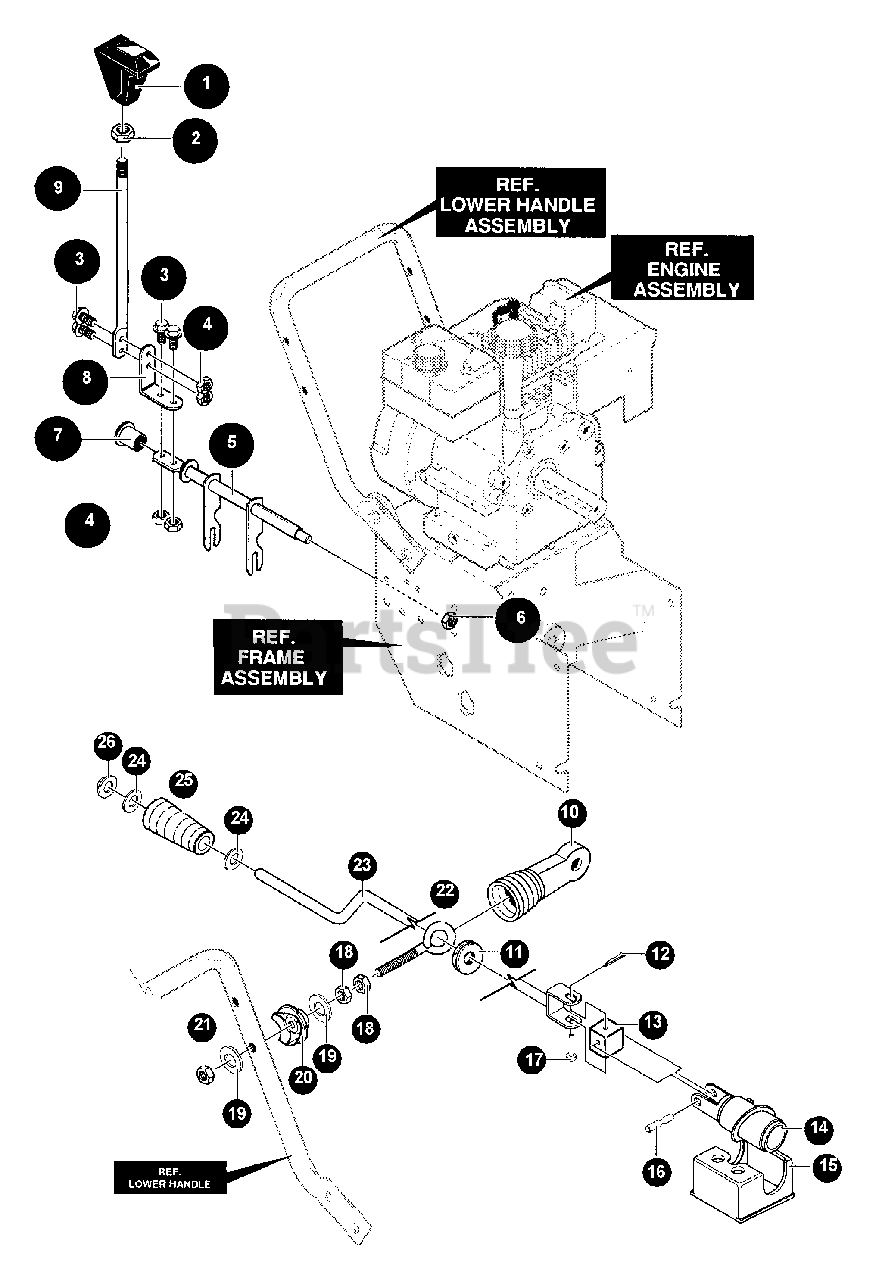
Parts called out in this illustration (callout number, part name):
1	KNOB, SHIFT
2	NUT - 1/2-13
3	SCREW - 1/4-20 X 5/8"
4	NUT - 1/4-20
5	YOKE ROD ASSY
6	NUT - 3/8-16
7	BEARING, FLANGE
8	LEVER, SPRING
9	ROD, SHIFT
10	BOOT, EYEBOLT CHUTE
11	GROMMET, EYE BOLT
12	PIN, SPLIT
13	BLOCK, UNIV PIV
14	GEAR - WORM
15	BRACKET, WORM MTG
16	PIN, U-JOINT
17	PIN, CLEVIS
18	NUT - 3/8-16
19	WASHER
20	ADAPTOR, BOOT
21	LOCKNUT - 3/8-16
22	BOLT - 3/8-16X5 -- EYE
23	CRANK, CHUTE
24	WASHER, FLAT .39X.70X.05
25	HANDLE, CHUTE CRANK
26	RING, RETAINING
